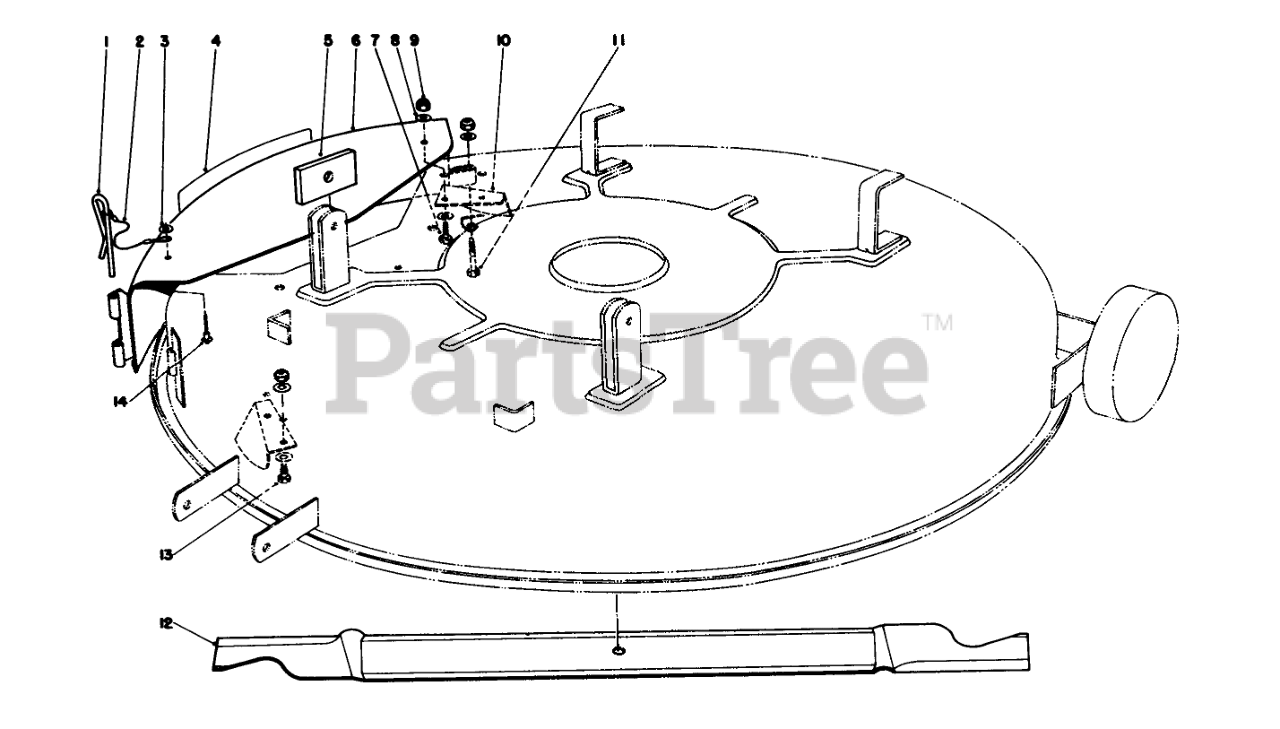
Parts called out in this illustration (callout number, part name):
1	PIN-LOCKING, CHUTE
2	LANYARD
3	WASHER-PLAIN
4	COVER DECAL
5	SPACER
6	Cover-Mulcher Assembly (Incl. Ref. #1 4 & 14)
7	SCREW-HH
8	WASHER-PLAIN
9	NUT-LOCK, NI
10	KICKER B
11	SCREW-HH
12	Blade
13	SCREW-HH
14	RIVET-BLIND
